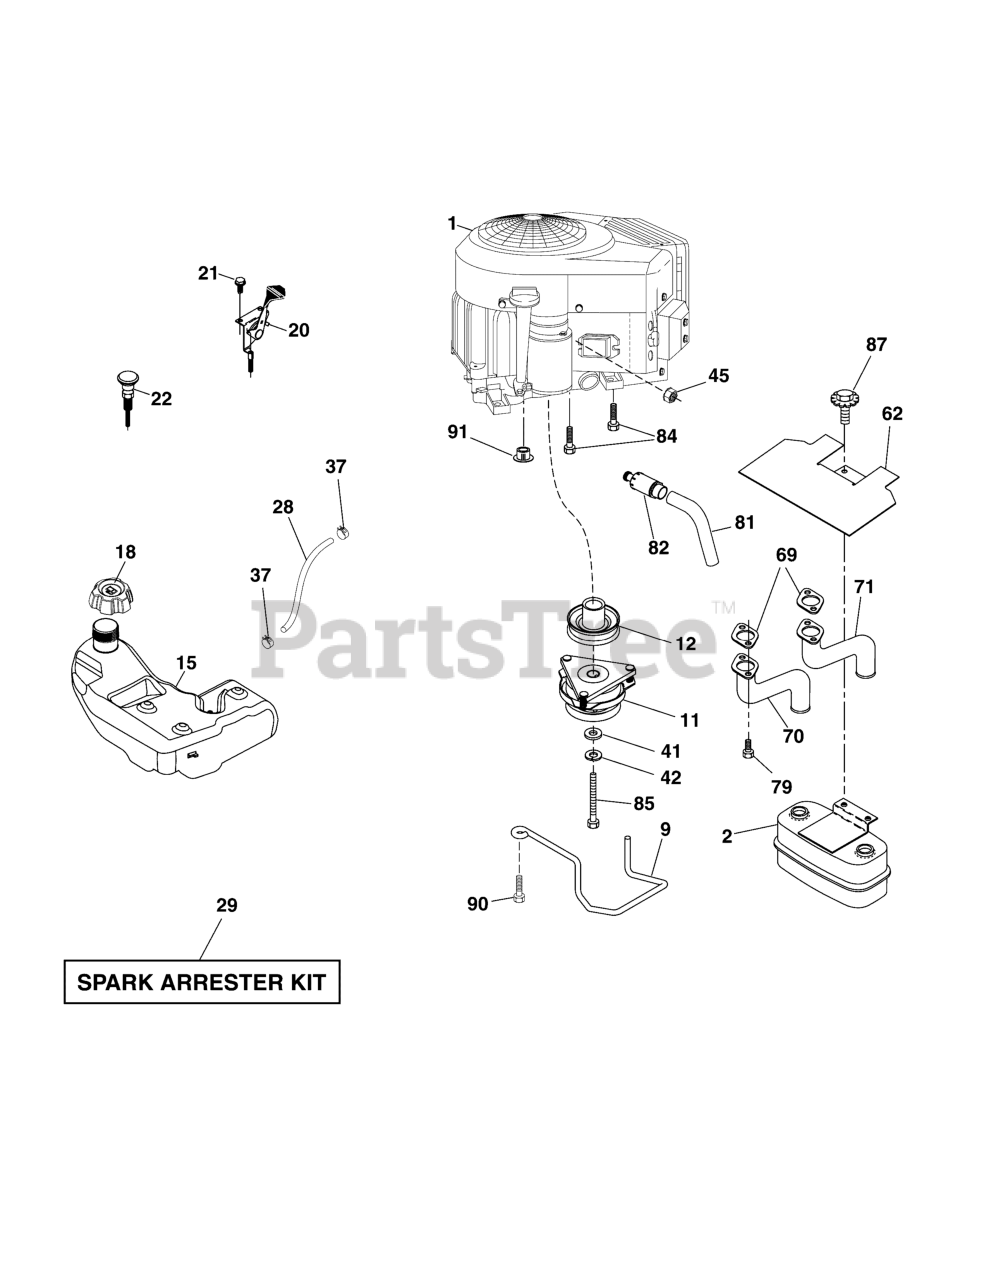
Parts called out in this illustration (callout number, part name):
1	ENGINE, 22HP Briggs & Stratton
2	Muffler
9	Keeper Belt Engine
11	Clutch Electric
12	Pulley Engine
15	Tank Fuel 3.0
18	Cap Asm
20	Control Throttle
21	Screw #10 x 0.750
22	Control Choke
28	Fuel Line
29	Spark Arrester Kit
37	Clamp Hose
41	Washer 1-1/2 OD x 15/32 ID x .250
42	Washer Lock 7/16
45	Nut Keps Hex 1/4-20 unc
62	Shield Heat Muffler
69	Gasket
70	Exhaust Tube LH
71	Exhaust Tube RH
79	Screw Socket Head 5/16-18 x 1
81	Tube Drain Oil Easy
82	Valve Drain Oil
84	Screw 3/8-16 x 1-1/4
85	Bolt Hex 7/16-20 x 4 5 Ga. 1.5
87	Bolt 5/16-18 unc x 3/4 w/Sems
90	Screw 3/8-16 x 1
